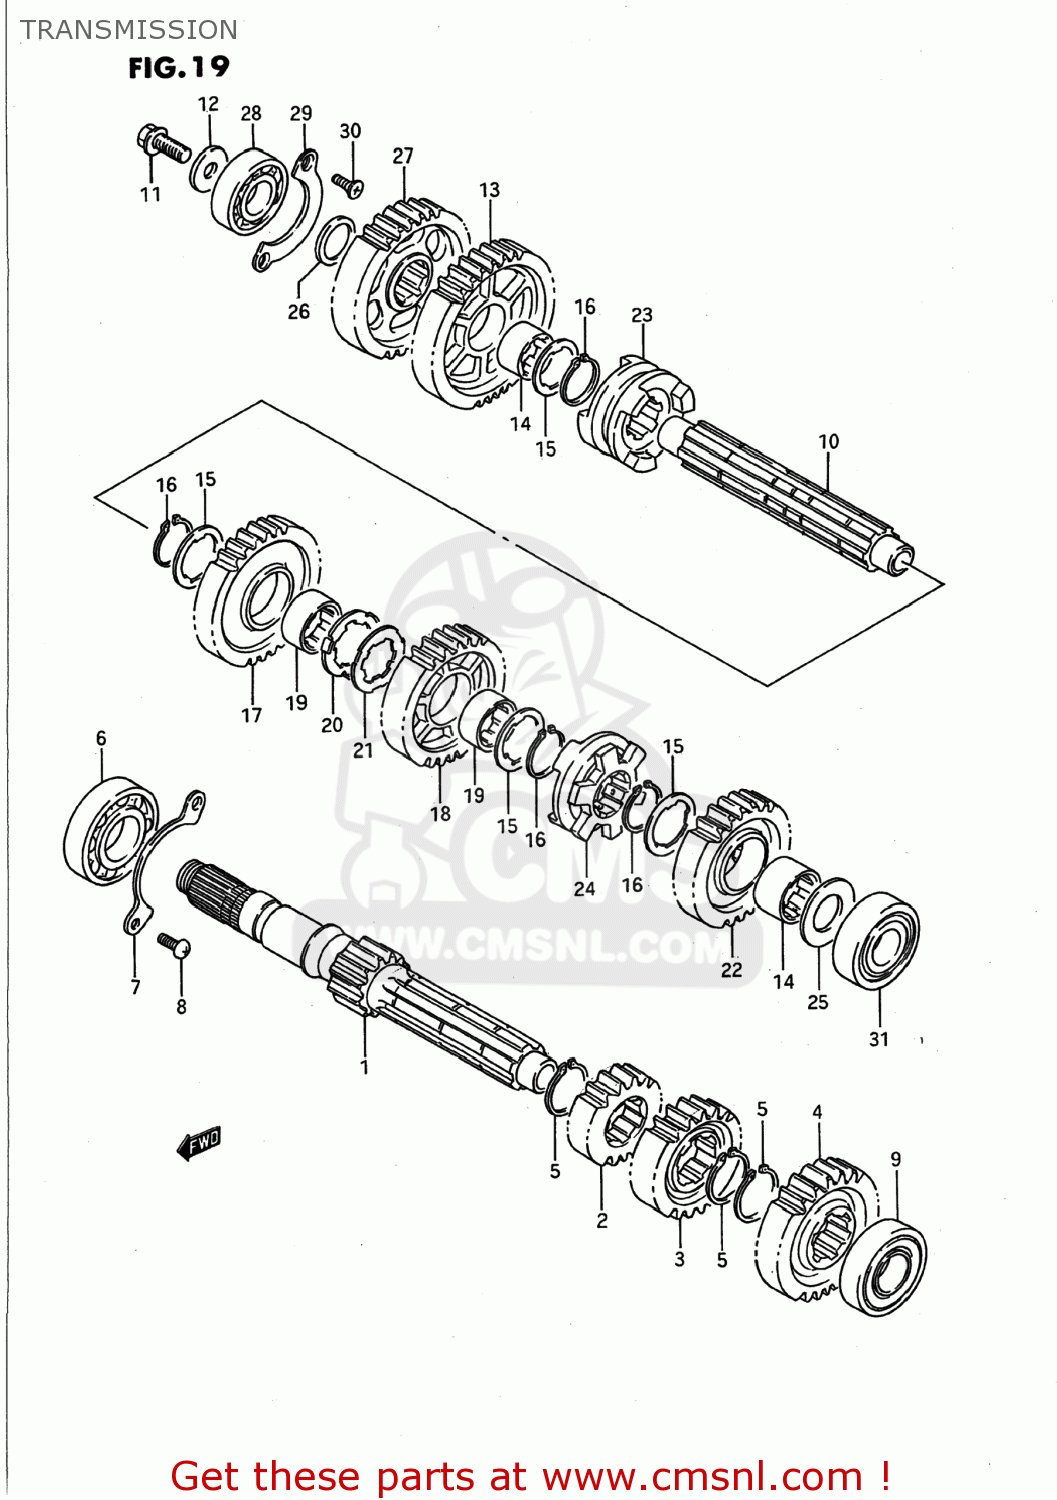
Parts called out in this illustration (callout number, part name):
1	SHAFT,COUNTER
2	GEAR,SECOND DRIVE
3	GEAR,3RD DRIVE
4	GEAR,FOURTH DRIVE
5	CIRCLIP
6	BEARING(25X62X17)
7	RETAINER,CNTR SHAFT BEARING
8	SCREW
9	BEARING(20X52X15)
10	SHAFT,DRIVE
11	BOLT(10X24)
12	WASHER
13	GEAR,FIRST DRIVEN
14	BUSH
15	WASHER,LOCK
16	CIRCLIP
17	GEAR,SECOND DRIVEN
18	GEAR,3RD DRIVEN
19	BUSH,3RD DRIVEN GEAR
20	WASHER
21	WASHER,LOCK
22	GEAR,FOURTH DRIVEN
23	DOG,SLIDING NO.1
24	DOG,SLIDING NO.2
25	WASHER
26	WASHER(22X32X3)
27	GEAR,OVER DRIVING DRIVE(NT:34)
28	BEARING(22X56X16)
29	RETAINER,CNTR SHAFT BEARING
30	SCREW
31	BEARING(20X52X15)
